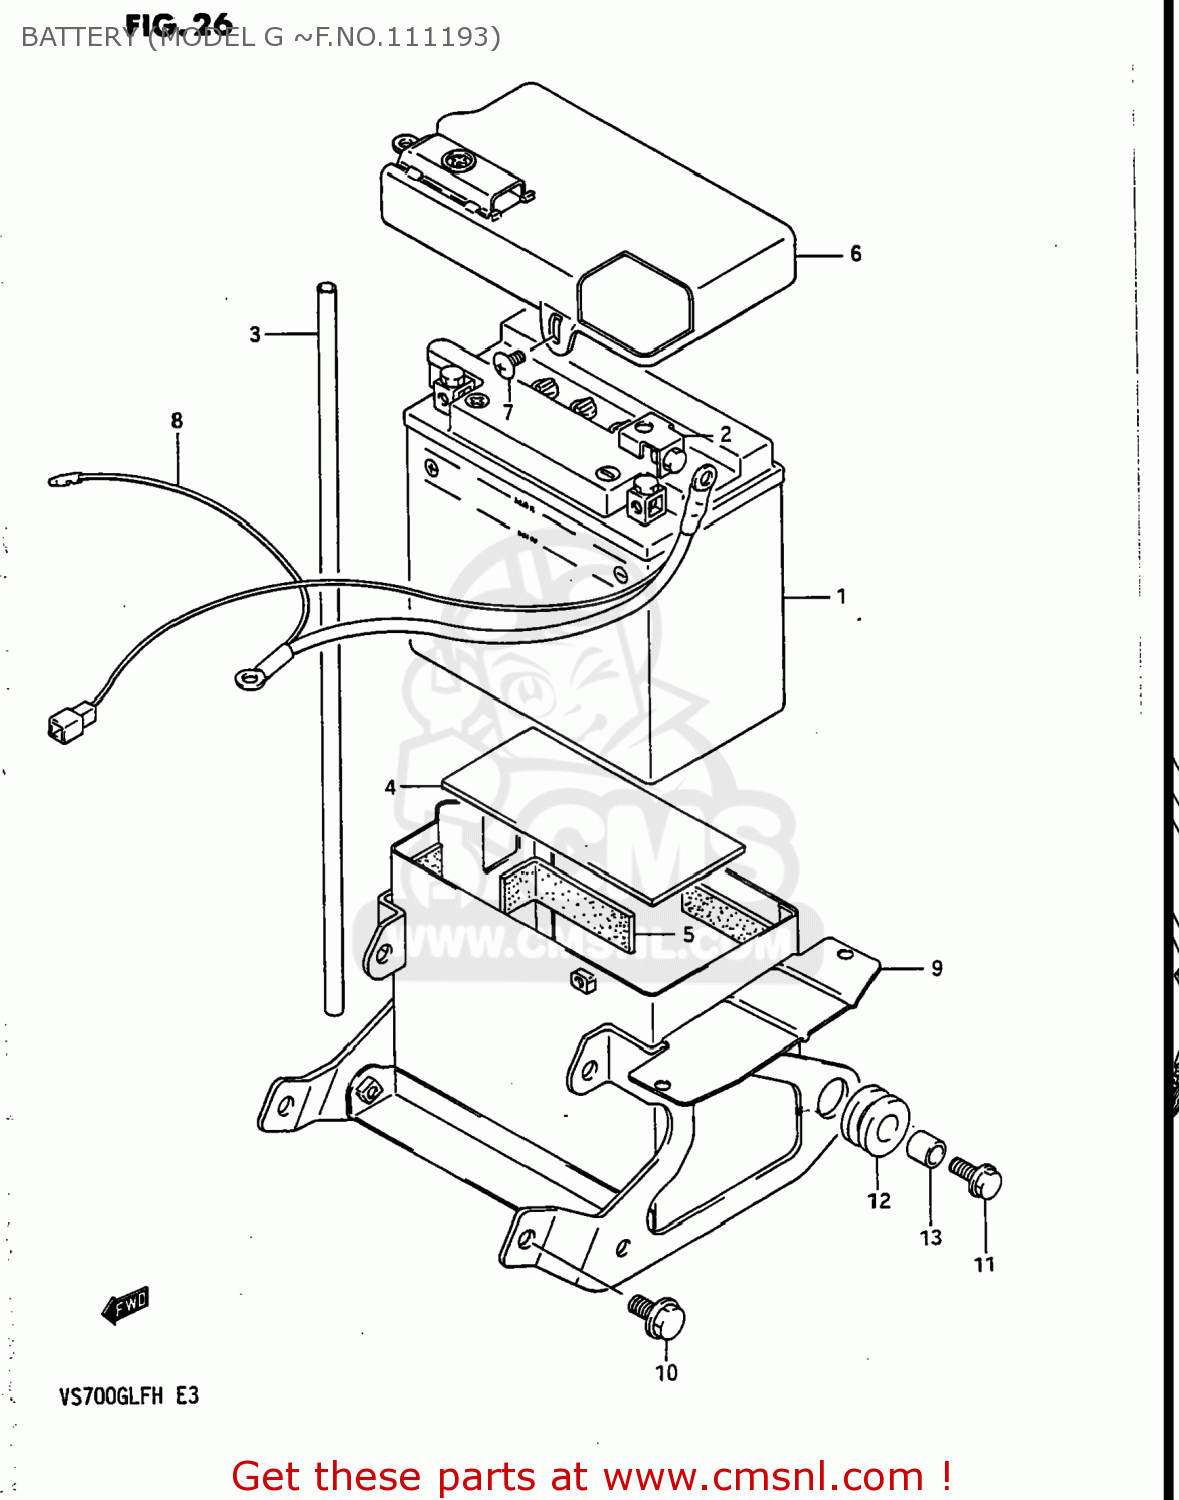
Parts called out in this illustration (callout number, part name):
1	BATTERY ASSEMBLY
2	TERMINAL,BATTERY
3	HOSE,BATTERY EXHAUST
4	PROTECTOR(170X95X3.0)
5	PROTECTOR(20X90)X2
6	COVER,BATTERY,UPPER
7	SCREW
8	WIRE,BATTERY MINUS LEAD
9	HOLDER,BATTERY
10	BOLT, LOWER
11	BOLT
12	CUSHION
13	SPACER (8.8X12X11)
